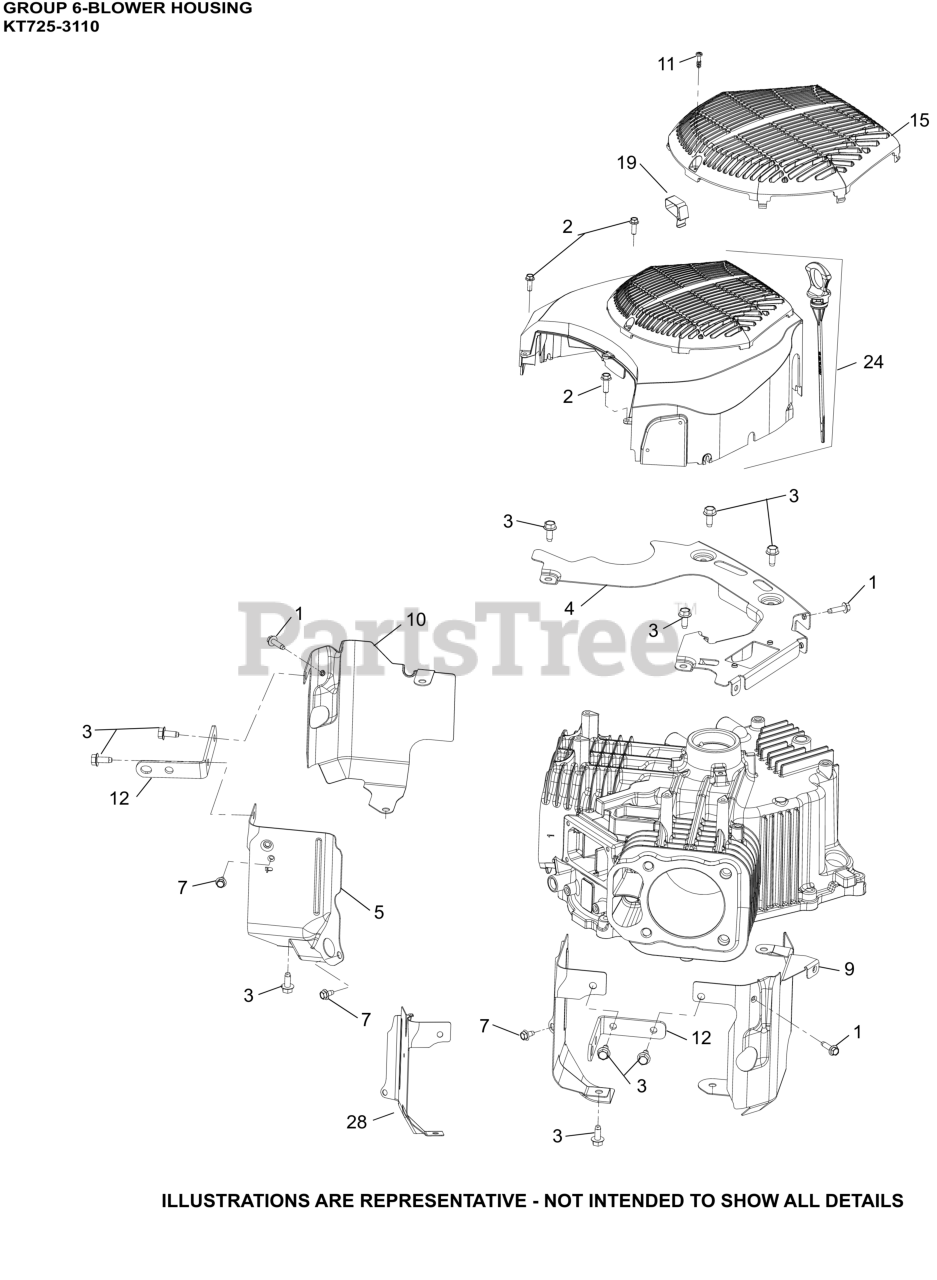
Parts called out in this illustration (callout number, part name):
1	SCREW, THD FRM-USE 25 086 473-S
2	SCREW, HI-LOW
3	SCREW, THREAD FORMING
4	PLATE, BACKING
5	BAFFLE, VALLEY #1
7	SCREW, THREAD FORMING
9	BAFFLE, LEFT BARREL
10	BAFFLE, RIGHT BARREL
11	SCREW, M5-2.42 (PT) THREAD
12	STRAP, LIFTING
15	GUARD, FIXED
19	CLIP, BLOWER HOUSING
24	KIT, BLOWER HOUSING
28	BAFFLE, VALLEY #2
